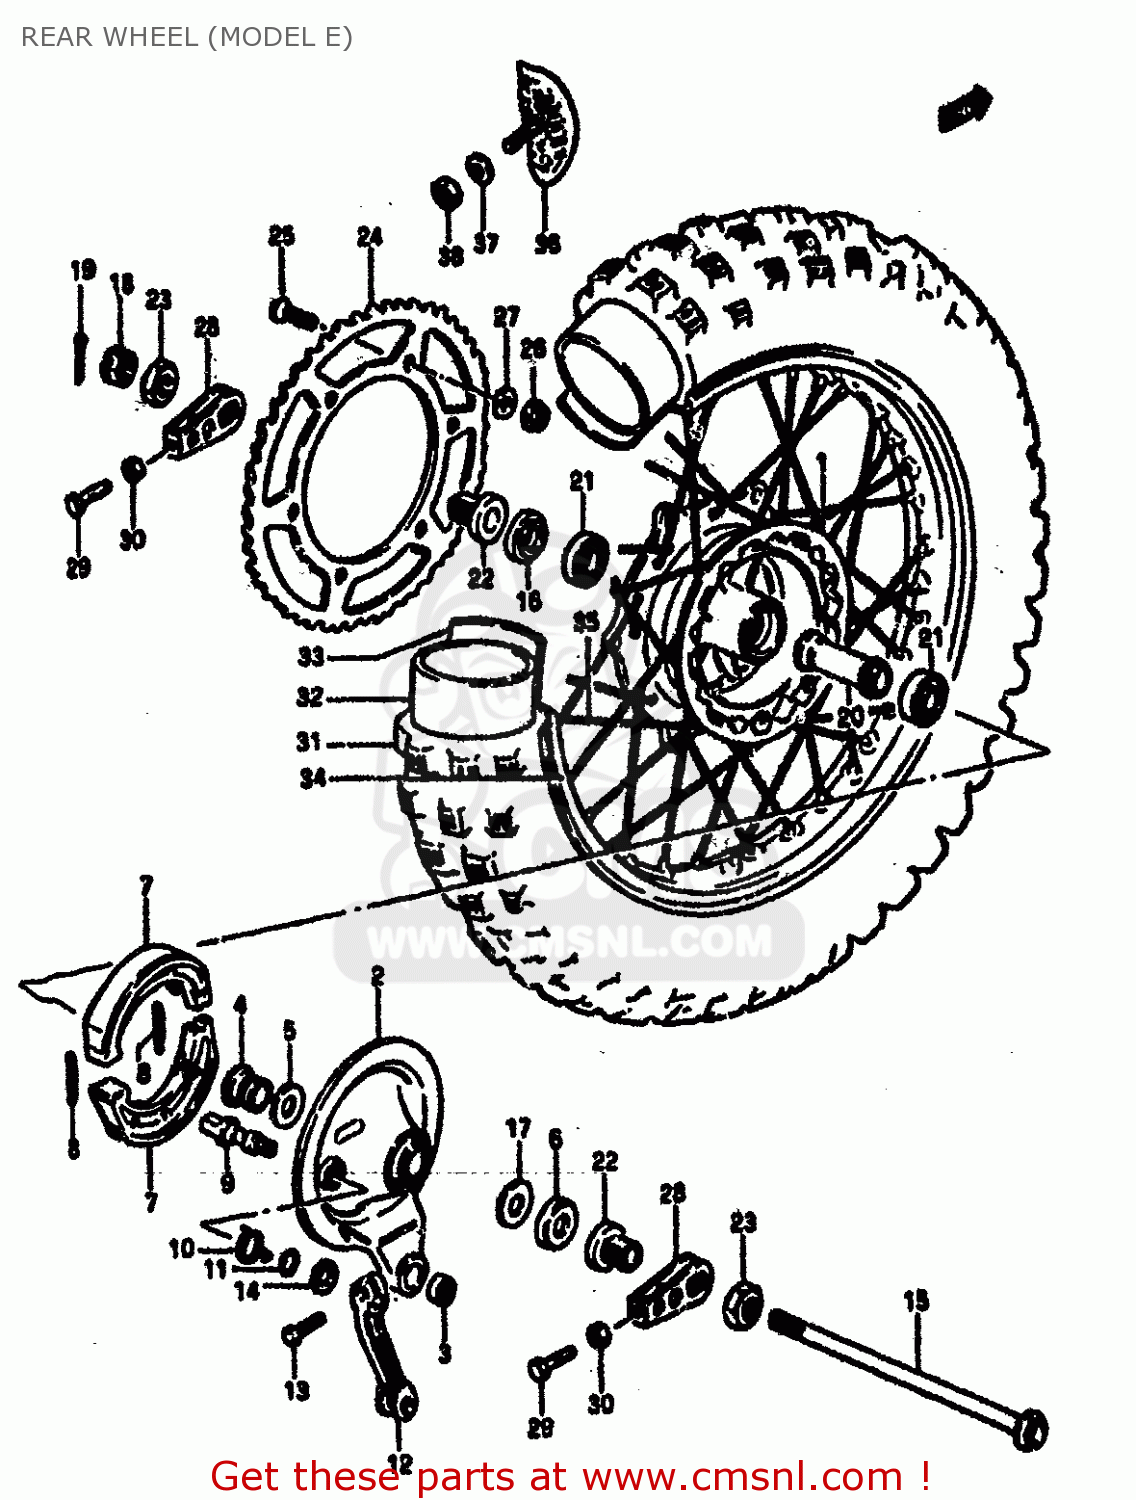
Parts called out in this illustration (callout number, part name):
1	DRUM,REAR HUB
2	PANEL SET,REAR HUB
3	SPHERICAL BRNG,TORQUE LINK
4	SPACER,RR BRAKE ANCHOR PANEL
5	SEAL,OIL(20X27X5)
6	CVR,RR BRAKE AHR PNL DUST SEAL
7	SHOE,BRAKE (MCA)
8	SPRING(L:34)
9	CAM,FR BRAKE
10	SPRING
11	O RING(D:2.5,ID:11.4)
12	LEVER,REAR BRAKE CAM
13	BOLT
14	WASHER(12.5X20X1)
15	AXLE,REAR
16	SPACER,RR AXLE,L
17	WASHER,THRUST
18	NUT
19	COTTER PIN
20	SPACER
21	BEARING
22	SPACER,CHAIN ADJUSTER
23	NUT
24	SPROCKET,REAR
25	SCREW(8X33.5)
26	NUT
27	WASHER
28	ADJUSTER,CHAIN
29	BOLT
30	NUT
31	TIRE
32	TUBE ASSEMBLY,WHEEL,INNER
33	PROTECTOR
34	RIM,REAR WHEEL
35	SPOKE SET,REAR WHEEL
36	STOPPER,BEAD
37	WASHER
38	NUT
